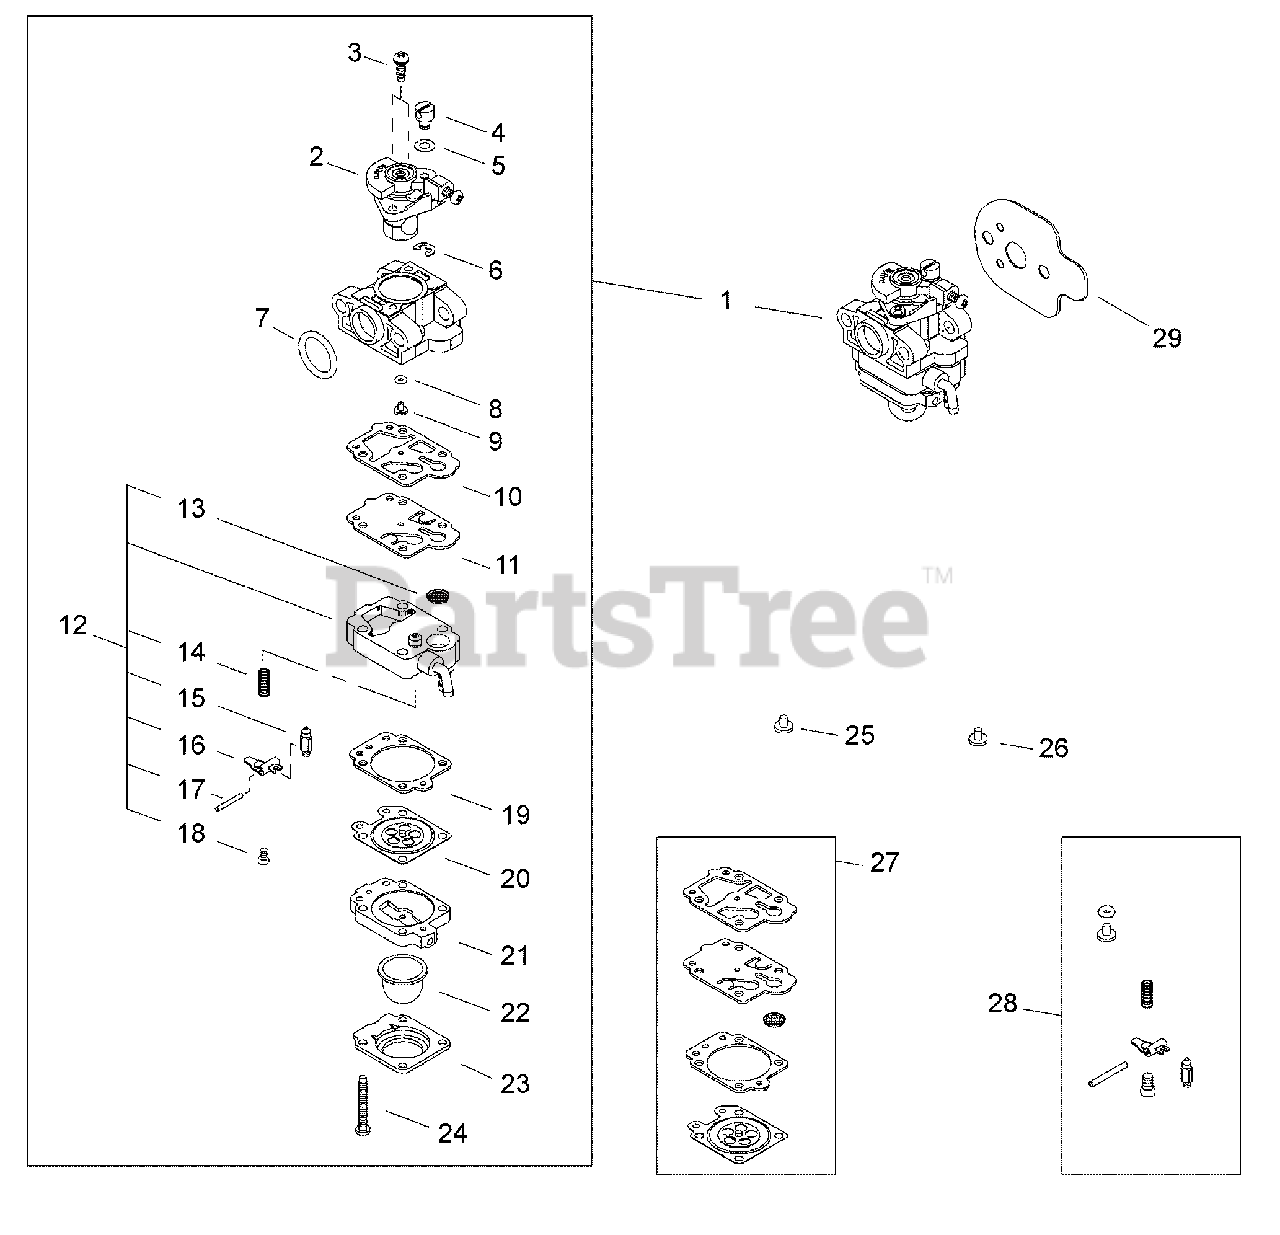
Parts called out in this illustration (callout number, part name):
1	CARBURETOR
2	THROTTLE VALVE ASSY
3	SCREW
4	SWIVEL
5	WASHER
6	RING, RETAINING
7	O-RING - 15
8	O-RING
9	JET, MAIN
10	GASKET, PUMP
11	DIAPHRAGM, PUMP
12	PUMP BODY ASSY
13	STRAINER
14	SPRING, METERING LEVER
15	VALVE, INLET NEEDLE
16	LEVER, METERING
17	PIN, METERING LEVER
18	SCREW, METERING LEVER PIN
19	GASKET, METERING
20	DIAPHRAGM, METERING
21	BASE, PURGE
22	BULB, PURGE
23	RETAINER, PURGE BULB
24	SCREW, PUMP COVER
25	JET, MAIN - 1000M
26	JET, MAIN - 2000M
27	DIAPHRAGM/GASKET KIT
28	INLET NEEDLE VALVE KIT
29	GASKET
